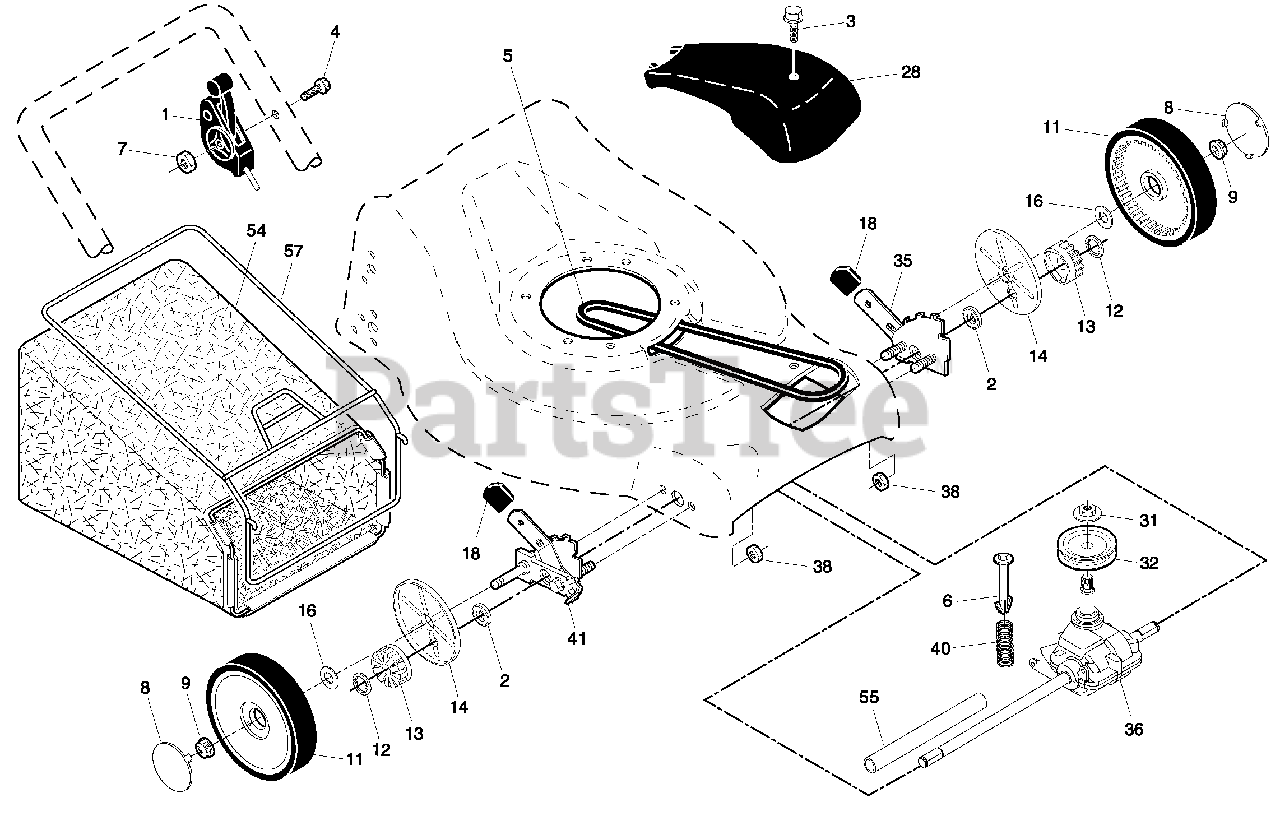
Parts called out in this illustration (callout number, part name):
1	Upper Handle
2	Lower Handle
3	Control Bar
4	Engine Zone Control Cable
5	Handle Bolt
6	Handle Knob
7	Hairpin Cotter
8	Wire Tie
9	Kit, Rear Door
10	Pop Rivet
11	Support Bracket, LH
12	Support Bracket, RH
13	Screw 1/4-20 x 5/8
14	Handle Bracket Assembly, LH
15	Handle Bracket Assembly, RH
16	Spring, Rear Door, LH
17	Spring, Rear Door, RH
18	Keps Locknut 1/4-20
19	Rope Guide
20	Rear Skirt
21	Hinge Screw 1/4-20 x 1-1/4
22	Engine Pulley
23	Hi-Pro Key
25	Screw, Hex Head, Threaded, Rolled 3/8-16 x 1-1/8
26	Hex Nut, Flanged
27	Wheel
28	Shoulder Bolt 5/16-18 x .33
29	Wave Washer
30	Axle Arm Assembly, Rear, RH
31	Selector Knob
32	Selector Spring
33	Nut, Hex 5/16-18
34	Axle Arm Assembly, Rear, LH
36	Bolt
37	Thread Cutting Screw w/Sems 5/16-18 x 3/4
38	Washer
41	Screw, Debris Shield
43	Debris Shield
44	Kit, Housing
45	Danger Decal
46	Blade Adapter
47	Blade, 21"
48	Hardened Washer
49	Helical Washer 3/8
50	Hex Head Machine Screw 3/8-24 x 1-3/8 Grade 8
51	Clamp, Cable
52	Screw, Cable Clamp
53	Screw
54	Throttle Control
59	Discharge Deflector
60	Hinge Bracket Assembly
61	Spring
62	Rod, Hinge
63	Nut, Hex
64	Mulcher Door
64	Operator's Manual, English
64	Operator's Manual, French
64	Repair Parts Manual, English / French
